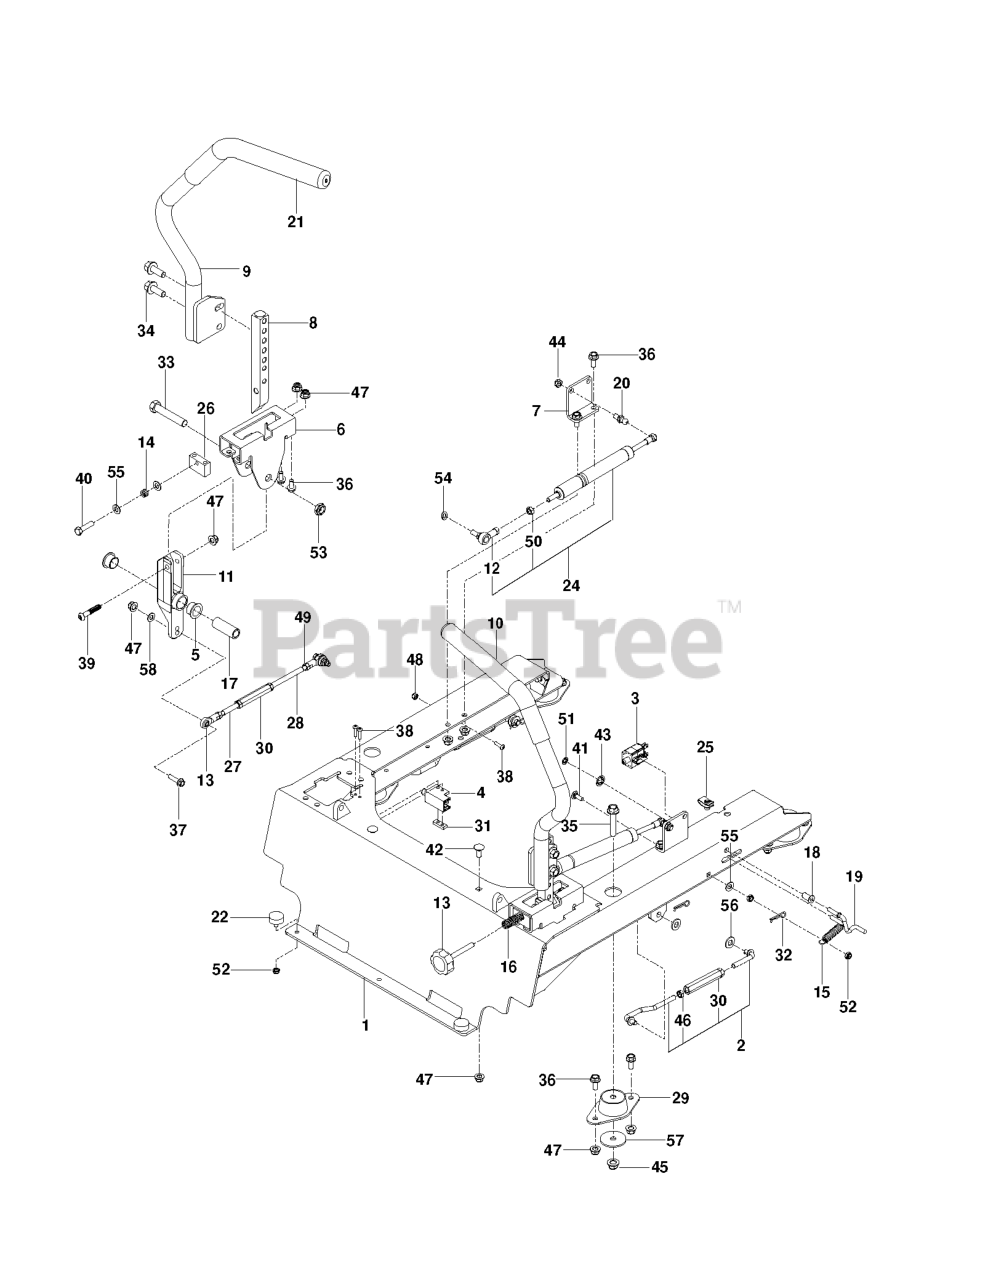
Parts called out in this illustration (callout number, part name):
1	FRAME SEAT MOUNT ORANGE
2	ASSEMBLY, SEAT STRUT
3	SWITCH, BRAKE 3P
4	SWITCH INTERLOCKT
5	BEARING, FLANGE
6	BRACKET, CONTROL
7	BRACKET.DAMPNER
8	LEVER, MOTION
9	LEVER.WITH GRIP.RT
10	LEVER.WITH GRIP.LT
11	LEVER.CONTROL.SHORT
13	BALL JOINT, RIGHT HANDED
15	SPRING, EXTENSION
16	SPRING COMPRESSION 2.0
17	SPACER, PIVOT CONTROL
18	BUSHING, 1/4 FLANGE
19	LINK, SWITCH
20	STUD.BALL.10MM
21	GRIP - DRIVE LEVER 12"
22	BUMPER, 1/4-20 STUD, 1/4
24	ASSEMBLY, DAMPENER
25	U-CLIP 5/16-18 NUT RETAINER
26	BLOCK.TRACKING
27	LINKAGE, CONTROL, FT
28	LINKAGE, CONTROL, RR
29	MOUNT, ISO
30	TURNBUCKLE, 3/8
31	TAPPED PLATE
32	HAIRPIN #2
33	HCS 1/2C X 2 3/4
34	HHFS 3/8-16 X 1 GRD 5 ZD
35	HHFS 3/8-16 X 2.0 GD 5
36	HHFS 5/16-18 X 3/4
37	HHFS 5/16-18 X 1.25 TPBLT GD 5
38	SCR #10-24 X .75 SKT HD BLK
39	SCREW 5/16-18 X 1 3/4 BTN-HD
40	HCS 5/16C X 1 1/4
41	RHSNB 1/4C X 3/4
42	BOLT 5/16C X 3/4" CARRIAGE
43	NUT 3/8 PALNUT RTNG BLK PHOS
44	NUT 5/16 NYLOC
45	NUT 3/8-16 HEX FLG NYLOC ZD
46	NUT 3/8-24 JAM
47	5/16-18 NYLOC FLANGE NUT
48	NUT 10-24 NYLOC
50	NUT M8 X 1.25 STD HEX
52	JAM NUT 1/4C (2 2 PW01)
53	NUT 1/2-13 HEX JM NYL
54	WASHER.LOCK.HVY.HLCL.SPR.5/16
55	FLAT WASHER 5/16 SAE
56	WASHER 3/8 SAE FLAT
57	WASHER, 3/8 SPEC
58	WASHER 5/16 FLAT
